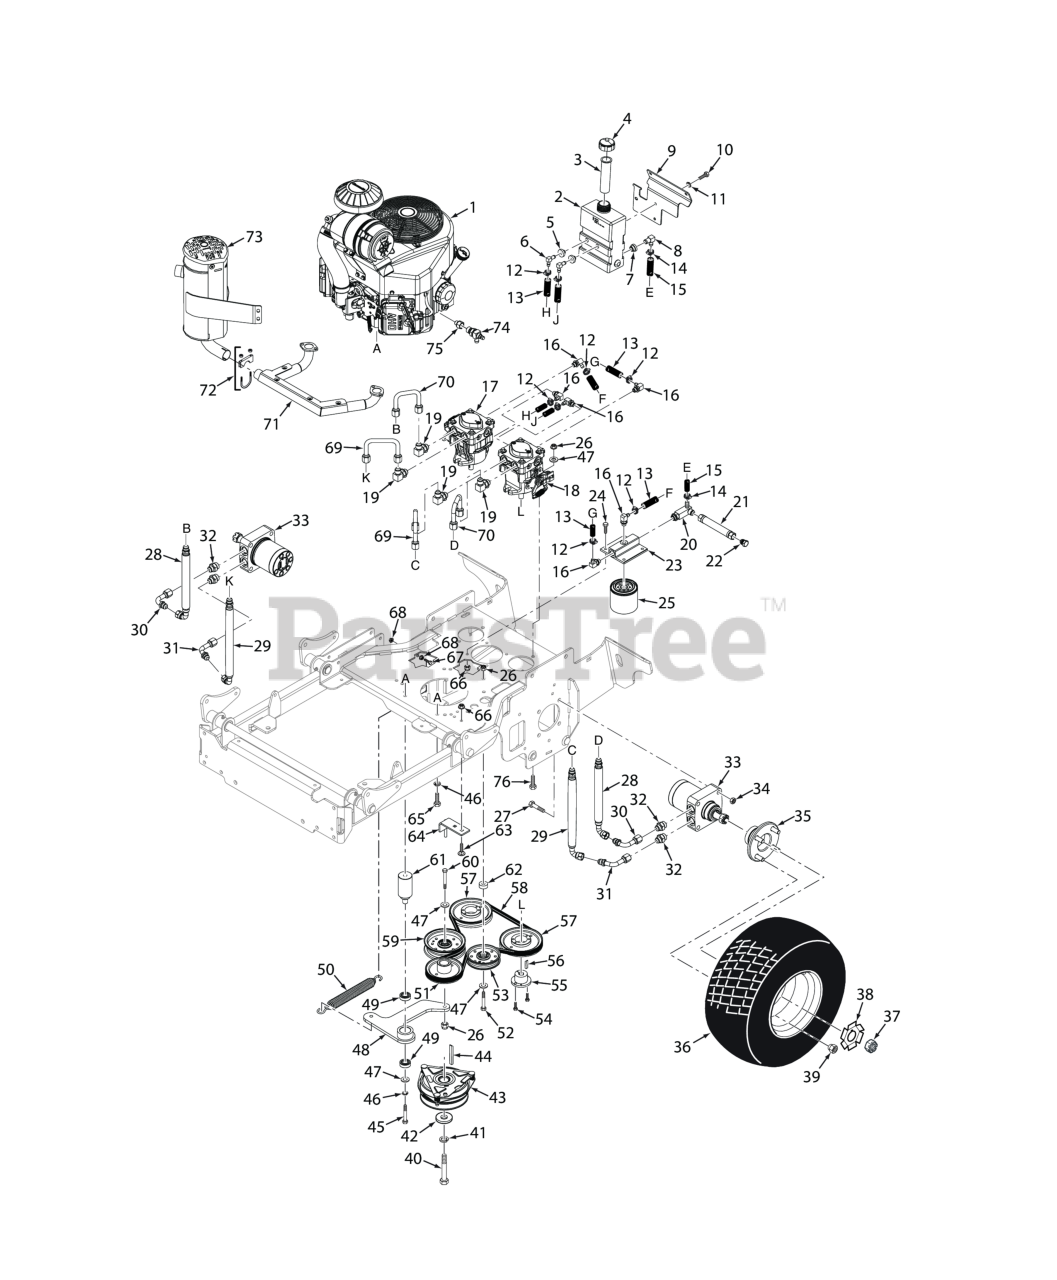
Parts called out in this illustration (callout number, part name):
1	Engine, 19hp Kawasaki FX600V
2	Hydro Tank Assy., SVRII
3	Insert, Filler Neck
4	CAP, HYDRAULIC TANK
5	Bushing, 0.56" Dia. Viton
6	Elbow, 90 Degree, 9/16-18 JIC x 9/16 O-Ring
7	Bushing, 0.78" Dia. Viton
8	Fitting, 90 Degree - 1/2" Hose
9	Bracket, Hydro Tank Mounting
10	BOLT, SERRATED FLANGE HEX HEAD 5/16-18 X 3/4"
11	Lockwasher, 5/16 (.317 x .586 x .078) Helical Spring
12	Clamp, .69" Max. / .25" Min. Dia.
13	Hose, 3/8" ID - 10-1/4" Long (Order By The Inch)
14	Clamp, Cable 3/4" I.D.
15	Hose Assembly, 1/2" ID (Oil Reservoir to Filter Base)
16	Elbow, 90 Degree - 9/16" O-Ring x 3/8" Hose
17	Pump, LH - 10cc (36 Only)
18	Pump, RH - 10cc (36 Only)
19	Elbow, 90 Degree 3/4-16 JIC x 3/4-16 O-Ring
20	Tee, 3/4" O-Ring
21	Drain Hose Assy.
22	Plug, JIC 3/4-16 UNF
23	Filter Head Assembly
24	BOLT, SERRATED FLANGE HEX HEAD 5/16-18 X 3/4"
25	OIL FILTER, SPECIAL
26	HEX NUT, ELASTIC STOP LOCK, 3/8-16
27	Bolt, Hex Hd. 1/2-13 x 2-1/2" (lower)
28	Hose Assy., 11-1/4"
29	Hose Assy., 13-1/4"
30	Tube Assy., 1/2 x 2 x 2"
31	Tube Assy., 1/2 x 2 x 3-1/4"
32	TUBE UNION, 3/4-16 JIC TO 7/8-14 "O" RING
33	Wheel Motor
34	Locknut, Hex 1/2-13 Center Lock
35	Wheel Hub Assembly
36	Wheel Assy., 20 x 8 - 10
37	HEX CASTLE NUT, 3/4-28 UNEF
38	Lock Washer, Wheel Motor
39	Wheel Nut, 1/2-20 x 13/16
40	Bolt, Hex Head 7/16-20 x 2-1/4" w/Patch (Kawasaki)
41	Lockwasher, 7/16� Spring
42	Flatwasher, 7/16-.469 x 1.75 x .25 (48, 52)
43	Clutch w/Tag GT2.5-FE02 (48 / 52)
44	Key, 1/4 x 1/4 x 3-1/2"
45	Capscrew, Hex Head 3/8-16 x 3-3/4"
46	Lockwasher, 3/8" Spring, Kawasaki FX / FT & FT-EFI / B&S 32BV
47	Flatwasher, 3/8 (.391 x .938 x .105 HD) Grade 8
48	Idler Arm Assy., Pump Drive
49	BEARINGS, BALL, NEUTRAL RETURN
50	Spring, Transmission Idler
51	Pulley, 4-3/4" OD - 1.125 Bore
52	Bolt, Hex Head 3/8-16 x 2-1/4" - 61"
53	Pulley, Idler 4� Dia.
54	Bolt, Hex Head 1/4-20 x 1" Grade 8 Black
55	Hub, Tapered, 15mm Bore
56	KEY, 5 MM X 5 MM X 25 MM
57	Pulley, 5.45 OD - Tapered Bore"
58	Belt, Pump Drive - SVRII-36
59	Pulley, 4" Dia. Idler
60	Bolt, Hex Head 3/8-16 x 2-1/4" - 61"
61	Pivot, Idler
62	Spacer, Idler Pulley - SFZ61
63	Bolt, 5/16-18 x .75 RHSN Carriage
64	ANTI-ROTATION WLMT, SVRII
65	Bolt, Hex Head 3/8-16 x 1-1/4", Kawasaki FX / FT & FT-EFI
66	Nut, Serrated Flange 5/16-18 (Right Front Engine Mounting, Briggs and Kohler Only)
67	Bolt, Hex Head 3/8-16 x 1-1/2" Grade 8 Black
68	NUT, 3/8-16 SERRATED FLANGE HEX HEAD
69	1/2" U-Tube Assembly, 4" Wide
70	Tube Assy., 1/2 x 2" Wide
71	Exhaust Manifold, 19 HP Kawasaki FX
72	Muffler Clamp
73	Muffler, Kawasaki (FS481, FS541, FS600)
74	Oil Drain, 35BV & 37BV-EFI - Briggs & Stratton
75	FITTING, M14 FEMALE TO M20 MALE
76	Bolt, Hex Head 3/8-16 x 1-1/2" B&S 32BV
